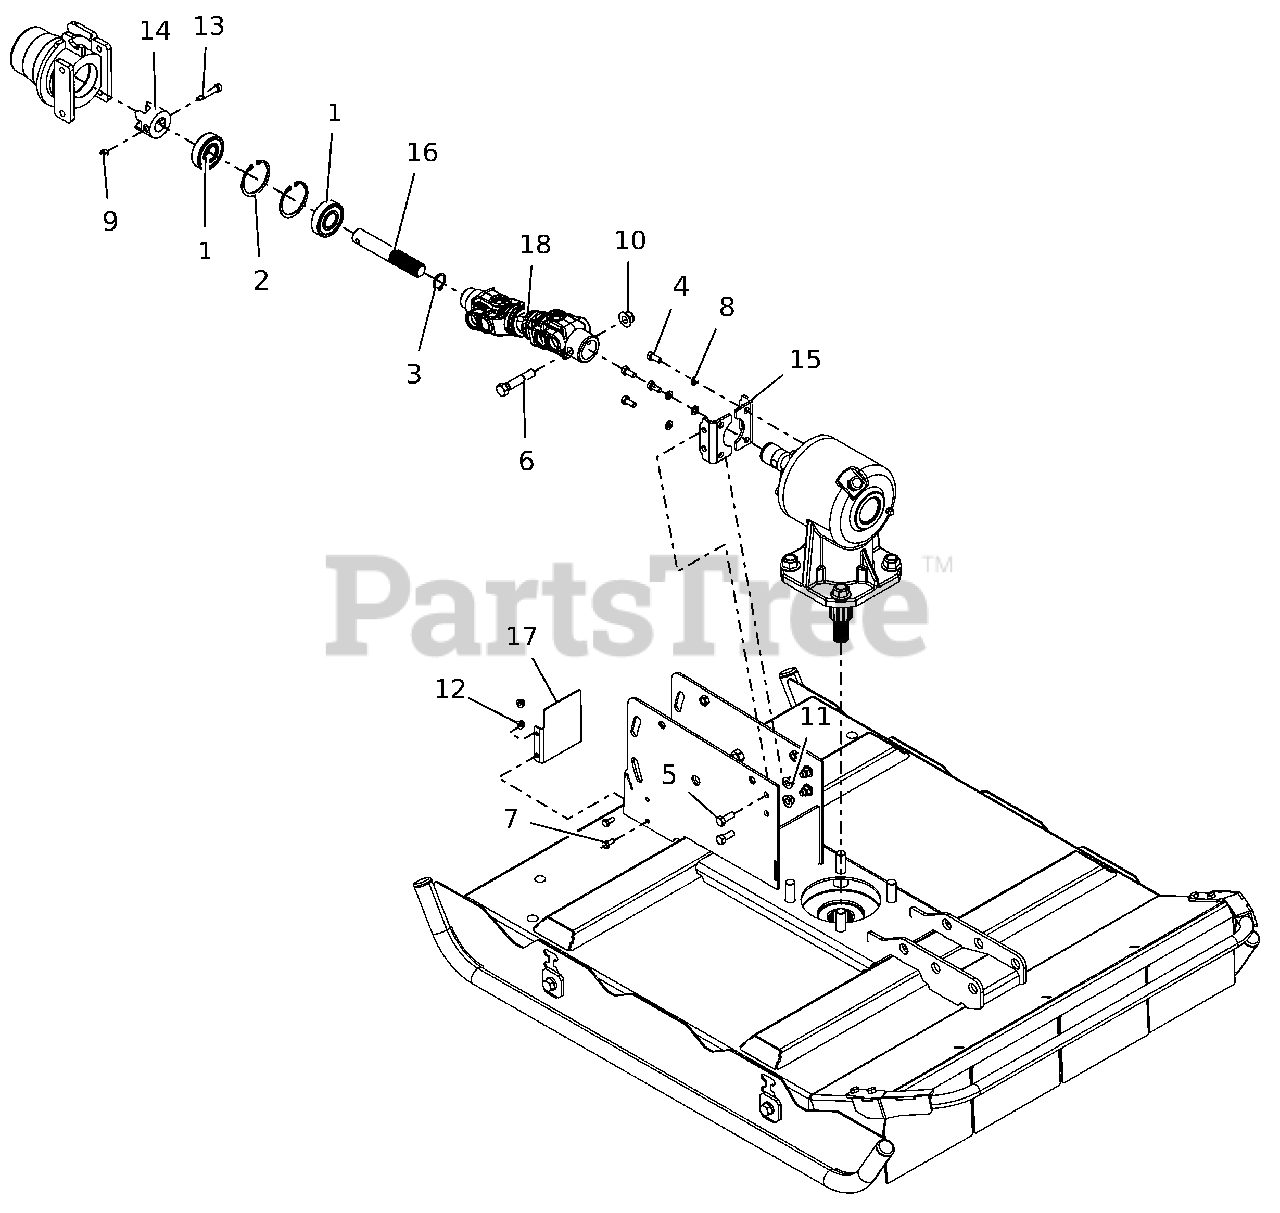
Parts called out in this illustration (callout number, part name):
1	BEARING, 6305LLC
2	RG-RTNG-INT 2.438X.078
3	RG-RTNG-EXT 1.00X.042
4	BLT,HEX .31-18X.75 G5 ZCC
5	BLT,HEX .38-16X1.00 G5 ZCC
6	BOLT, SHEAR 1/2-13 X 2.75
7	BLT, HEX .25-20X.625 G5 ZCC
8	WSHR,LK-REG .312X.078 ZCC
9	NUT,NYL M6-1.0 G8.8 ZCC
10	NUT,NYL-FLG .50-13 GF ZCC
11	NUT,NYL-FLG .38-16 GF ZCC
12	NUT,NYL-FLG .25-20 GF ZCC
13	BLT,SHLDR M8X35
14	CLAW COUPLING
15	BRKT, GEARBOX
16	PTO SHAFT
17	COVER, REAR
18	DRIVE LINE, 32" RC MOWER
